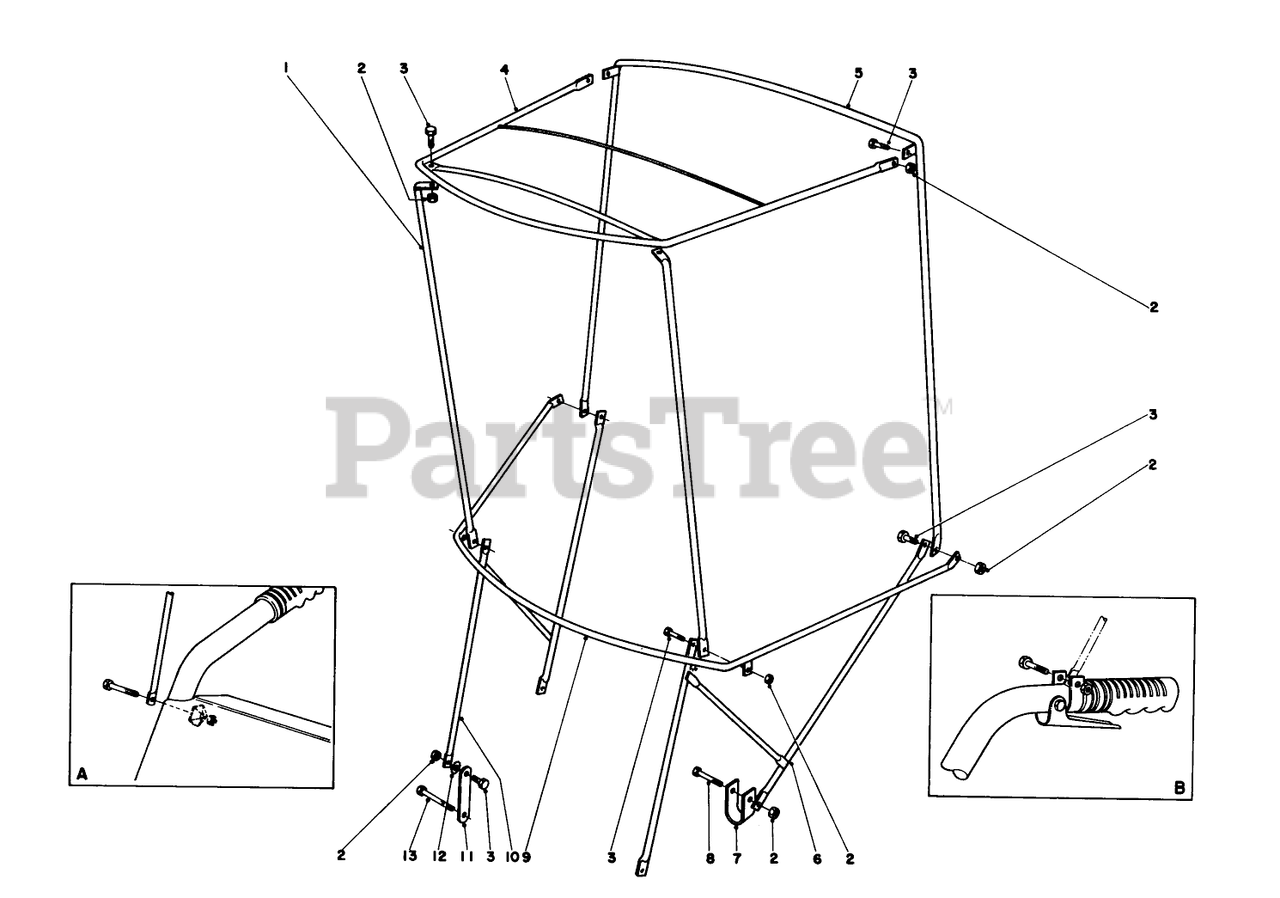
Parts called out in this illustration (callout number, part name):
3	SCREW-HH
8	SCREW-HH
12	WASHER-LOCK/EXT
13	SCREW-HH
